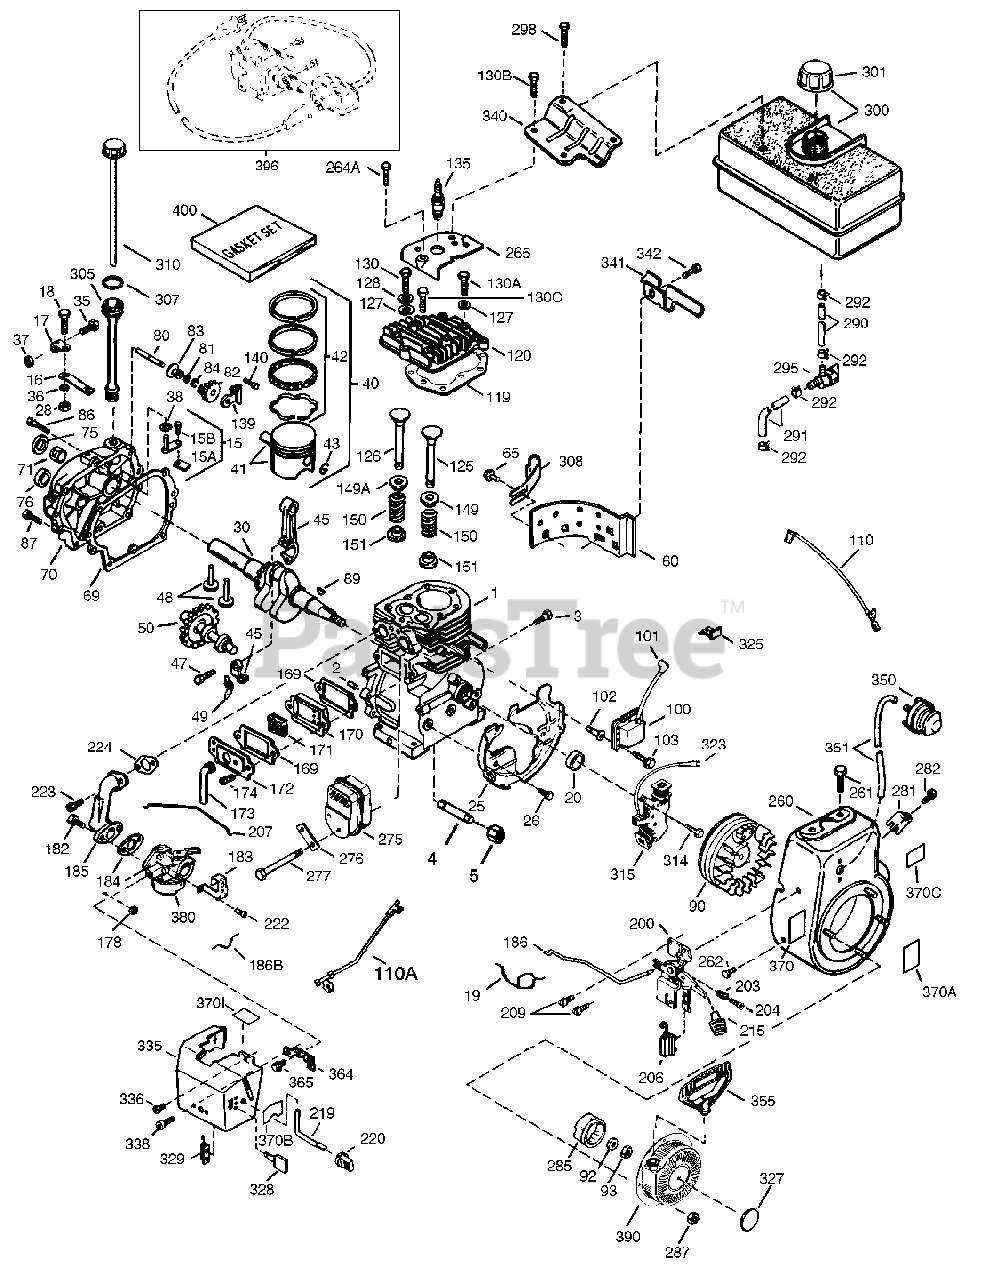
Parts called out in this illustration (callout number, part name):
1	Cylinder
2	Dowel Pin
3	Scrw, 1/4-20 x 1/2"
4	Oil Drain Extension
5	Extension Cap
15	Governor Rod
15A	Governor Yoke
15B	Screw, 6-40 x 5/16"
16	Governor Lever
17	Governor Lever Clamp
18	Screw, Torx T-15, 8-32 x 3/8"
19	Speed Control Spring
25	Blower Housing Baffle
26	Screw, 1/4-20 x 5/8"
28	Lock Nut, 10-32
30	Crankshaft
35	Screw, 10-32 x 3/4"
36	Lock Washer
37	Lock Nut, 10-32
38	Retaining Ring
40	Piston, Pin & Ring Set (Standard)
41	Piston & Pin Ass'y (Standard)
42	Ring Set (Standard)
43	Piston Pin Retaining Ring
45	Connecting Rod Ass'y
47	Connecting Rod Bolt
48	Valve Lifter
49	Oil Dipper
65	Screw, 10-24 x 1/2"
69	Cylinder Cover Gasket
70	Cylinder Cover
71	Crankshaft Bushing
80	Governor Shaft
82	Governor Gear Ass'y
83	Governor Spool
84	Retaining Ring
86	Screw, 1/4-20 x 1-3/16"
87	Screw, 1/4-20 x 1-11/16"
89	Flywheel Key
92	Lock Washer
93	Flywheel Nut
100	Solid State Ignition
101	Spark Plug Cover
102	Solid State Mounting Screw
103	Screw, Torx T-15, 10-24 x 15/16"
110	Ground Wire
110A	Ground Wire
119	Cylinder Head Gasket
120	Cylinder Head
125	Exhaust Valve (Standard)
126	Intake Valve (Standard)
128	Bell Washer
130	Screw, 5/16-18 x 1-3/4"
130A	Screw, 5/16-18 x 2"
130B	Screw, 5/16-18 x 1-1/2"
130C	Screw, 5/16-20 x 5/8"
135	Resistor Spark Plug (J8C/356)
139	Governor Gear Bracket
140	Screw, 10-24 x 1/2"
149	Valve Spring Cap
149A	Valve Spring Cap
150	Valve Spring
151	Valve Spring Keeper
169	Valve Cover Gasket
170	Breather Body
171	Breather Element
172	Valve Cover
173	Breather Tube
174	Screw, 10-24 x 1/2"
178	Nut and Lock Washer, 1/4-28
182	Screw, 1/4-20 x 1"
184	Carb. to Intake Pipe Gasket
185	Intake Pipe
186	Governor Link
186B	Choke Spring
200	Control Bracket
203	Compression Spring
204	Screw, Torx T-10, 5-40 x 7/16"
207	Throttle Link
209	Screw, 10-32 x 1/2"
215	Control Knob
219	Choke Rod
220	Choke Knob
222	Screw, 10-32 x 1/2"
223	Screw, Torx T-30, 5/16 -18 x 1-1/8"
224	Intake Pipe Gasket
260	Blower Housing
261	Screw, 5/16-18 x 3/4"
262	Screw, Torx T-40, 5/16-24 x 21/32"
264A	Screw, 1/4-20 x 5/8"
265	Cylinder Head Cover
276	Locking Plate
277	Screw, 5/16-18 x 4-3/16"
281	Starter Bubble Cover
282	Screw, 8-32 x 3/8"
285	Starter Cup
287	Nut & Lock Washer, 1/4 -28
290	Fuel Line
291	Fuel Line
292	Fuel Line Clamp
295	Fuel Shut-Off Valve
300	Fuel Tank
301	Fuel Cap
305	Oil Fill Tube
308	Fill Tube Clip
314	Screw, 1/4-20 x 3/4"
315	Alternator Coil (18 Watt)
325	Wire Clip
328	Key Switch (Push-In)
335	Carburetor Cover
336	Screw, 10-32 x 1/2"
338	Screw, 10-32 x 3/8"
340	Fuel Tank Bracket
341	Fuel Tank Bracket
342	Screw,1/4-20 x 5/8"
350	Primer Ass'y
351	Primer Line
355	Mitten Grip Starter Handle
364	Carburetor Cover Bracket
365	Screw, 8-32 x 27/64"
370	Identification Decal
370A	Throttle Decal
370B	Instruction Decal
370C	Primer Decal
370I	Warning Decal
380	Carburetor
390	Rewind Starter
396	Electric Starter
400	Gasket Set
